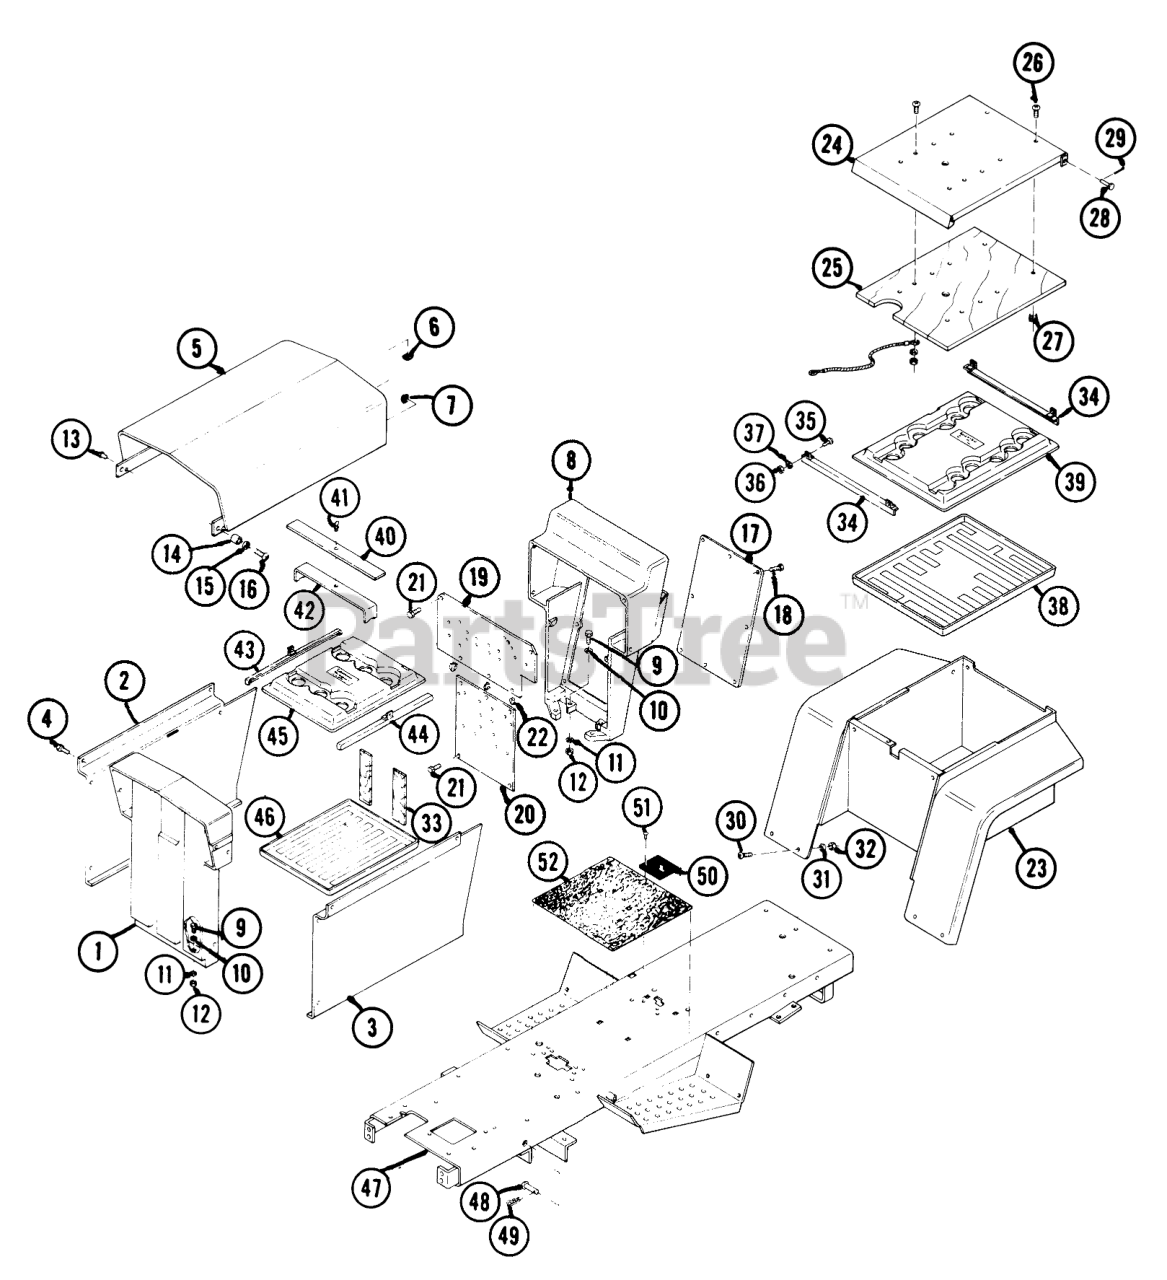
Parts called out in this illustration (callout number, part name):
8-01	Grill
8-02	Side Plate, Right Hand
8-03	Side Plate, Left Hand
8-04	Rivet
8-05	Hood Assembly
8-06	HOOD STOP
8-07	BUMPER
8-08	Control Cabinet (Hood Stand)
8-09	Bolt, Hex 5/16-18 x 1 1/4
8-10	Washer 5/16
8-11	Lockwasher-5/16
8-12	Nut, Hex 5/16-18
8-13	Rivet
8-14	Bushing
8-15	Washer
8-16	Machine Screw, Pan Head
8-17	Cover
8-18	Screw, Thd. Rolling #8-32 x 3/8
8-19	Upper Control Panel
8-20	Lower Control Panel
8-21	Thrd. Rolling Screw #8-32 x 1/2
8-22	Cable Tie
8-23	Rear Body Assembly (with Fenders)
8-24	Seat Pan
8-25	Stiffener, Seat Pan
8-26	Screw, Phillips Pan Head 5/16-18 x 3/4
8-27	"T" Nut, 243 A
8-28	Clevis Pin 1/8 x 3/4
8-29	Cotter Pin
8-30	Screw, Phillips Pan Head 1/4-20 x 1/2
8-31	Lockwasher 1/4
8-32	Nut, 1/4-20
8-33	Spacer, Battery
8-34	Battery Clamp, Rear Box
8-35	Mach. Screw #10-32 x 3/4
8-36	Nut #10-32
8-37	Lockwasher #10
8-38	Battery Tray, Rear Box
8-39	Battery Cover, Rear Box
8-40	Clamp Plate, Front Box
8-41	Thumb Screw, Clamp
8-42	Clamp, Front Box
8-43	Hold Down, Front Right
8-44	Hold Down, Front Left
8-45	Battery Cover, Front Box
8-46	Battery Tray, Front Box
8-47	Frame
8-48	Clevis Pin
8-49	Hairpin Cotter
8-50	Shift Plate
8-51	Rivet
8-52	Floor Mat
